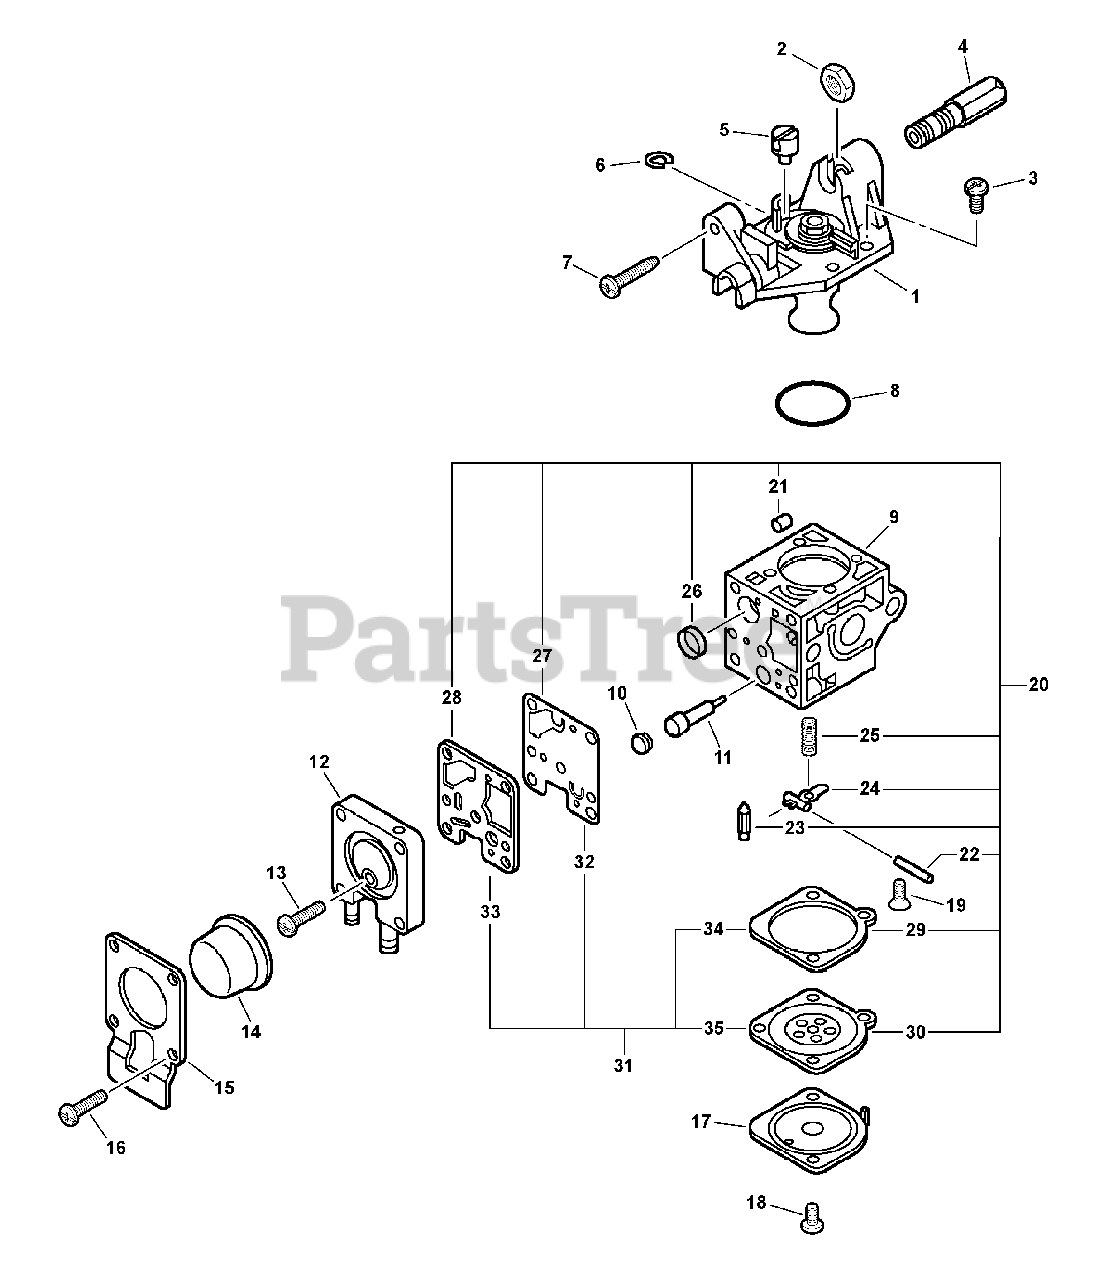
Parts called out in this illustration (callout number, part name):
1	COVER ASSY, ROTOR
4	ADJUSTER, THROTTLE CABLE
5	SWIVEL
7	SCREW, IDLE ADJUST
9	BODY, CARBURETOR
11	NEEDLE, HIGH SPEED
12	BODY ASSY, PURGE
14	BULB, PURGE
15	RETAINER, PURGE BULB
16	SCREW
17	COVER, METERING DIAPHRAGM
20	REBUILD KIT
21	GUIDE, ROLLER
22	PIN, METERING LEVER
23	VALVE, INLET NEEDLE
24	LEVER, METERING
25	SPRING
26	STRAINER
27	DIAPHRAGM, PUMP
28	GASKET, PUMP
29	GASKET, METERING
30	DIAPHRAGM, METERING
31	GASKET / DIAPHRAGM KIT
32	DIAPHRAGM, PUMP
33	GASKET, PUMP
34	GASKET, METERING
35	DIAPHRAGM, METERING
